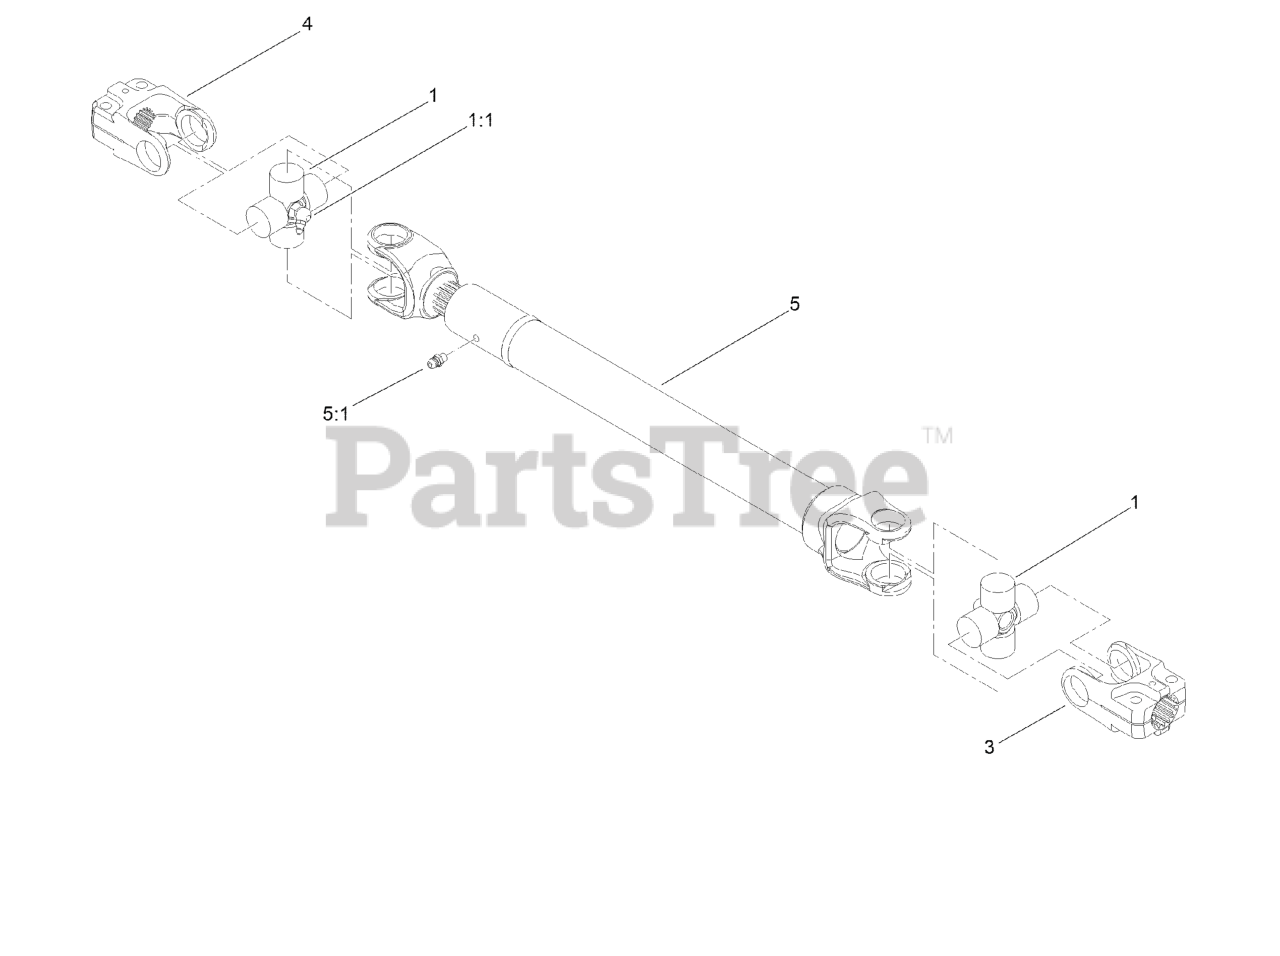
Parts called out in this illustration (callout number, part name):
1	CROSS AND BEARING KIT
1:1	FITTING-GREASE
3	YOKE-END
4	YOKE-END
5	Tube-Yoke, Slip
5:1	FITTING-GREASE
